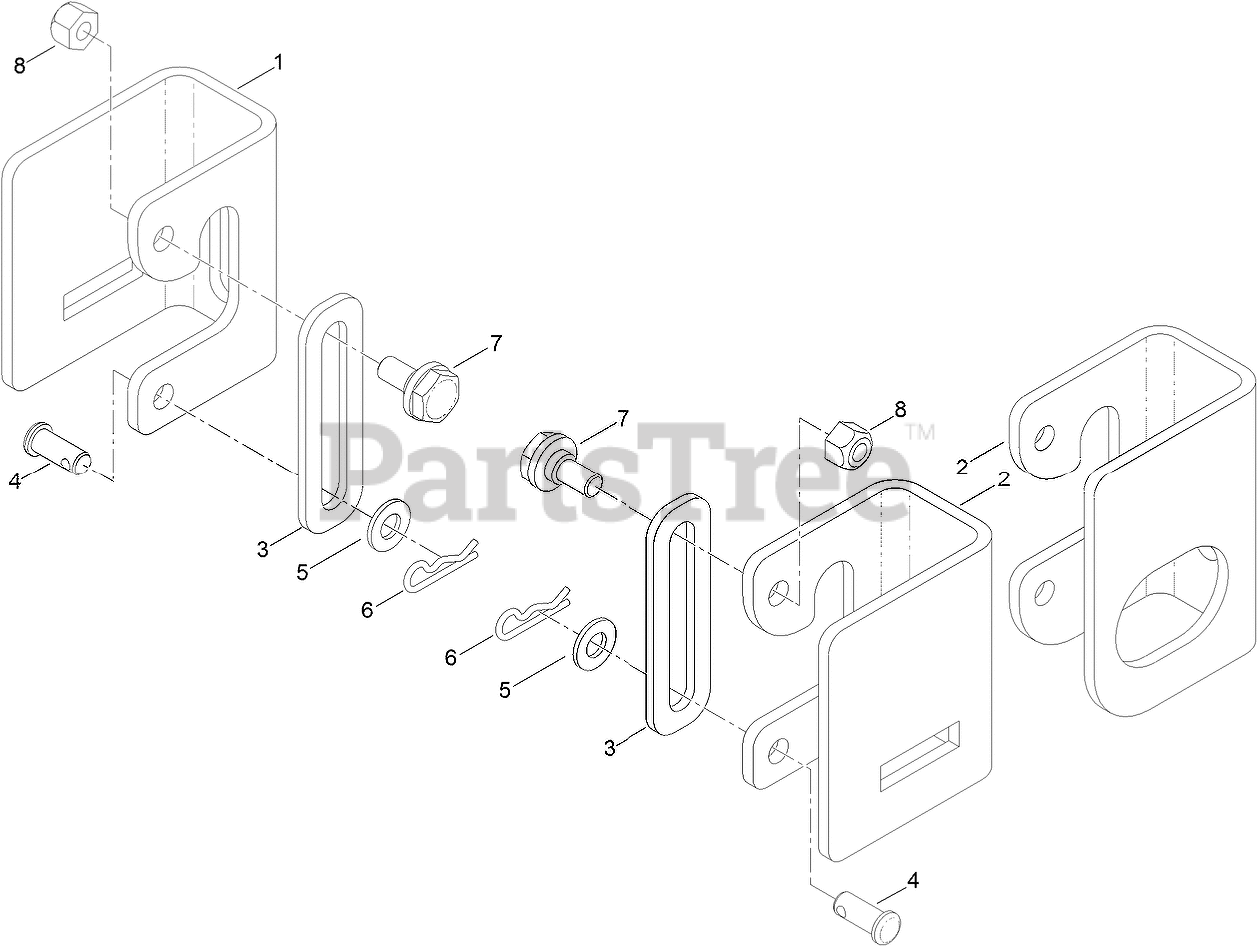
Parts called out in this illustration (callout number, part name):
1	BRACKET-HANGER, RH
2	BRACKET-HANGER, LH
3	LINK-RETENTION, DECK
4	PIN-CLEVIS
5	WASHER-PLAIN
6	PIN-COTTER
7	BOLT-SHOULDER
8	NUT-LOCK, NI
